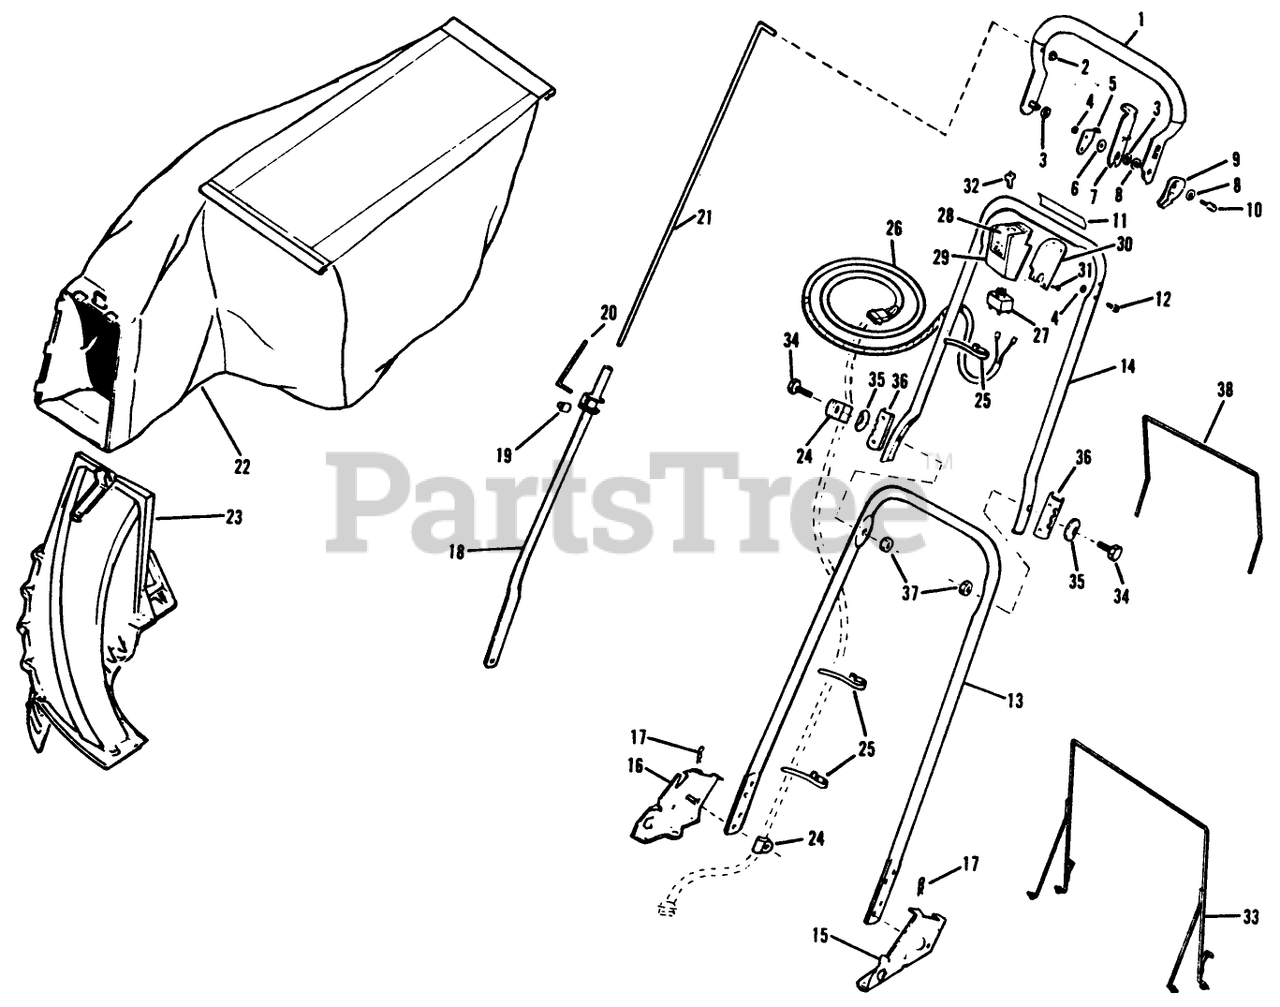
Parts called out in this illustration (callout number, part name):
1	Handle Grip Assy.
2	Palnut
3	WASHER M
4	LOCKNUT E
5	HANDLE STOP
6	WASHER
7	LEVER LOCKOUT
10	BOLT PIONEER
11	Decal
12	SCREW-HANDLE STOP
13	HANDLE SECTION *B
15	BRACKET ASM - HANDLE, SP, LH
16	BRACKET ASM - HANDLE, SP, RH
17	HAIR PIN
21	ROD CONTROL
27	ROTARY KEY SWITCH
28	Decal-Switch
29	HOUSING SWITCH
33	HANGER AY
35	WASHER-CURVED
36	BRACKET R/B 613462
37	LOCKNUT E
38	HANGER
